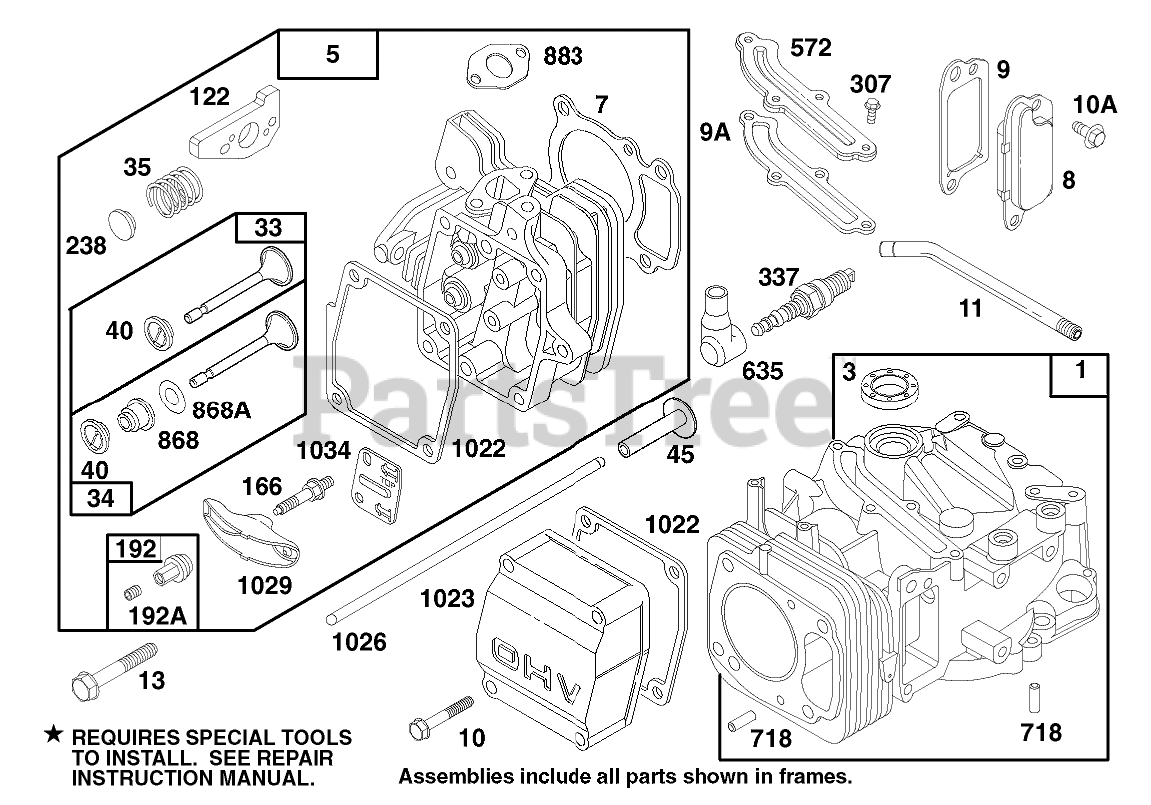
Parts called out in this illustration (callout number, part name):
1	CYLINDER ASSEMBLY
3	SEAL - OIL
5	CYLINDER HEAD
7	CYLINDER HEAD GASKET
8	BREATHER ASM
9	BREATHER GASKET
9A	GASKET-BREATHER
10	HEX HEAD SCREW
10A	HEX HEAD SCREW
11	TUBE - BREATHER
13	CYLINDER HEAD SCREW
33	EXHAUST VALVE
34	INTAKE VALVE
35	VALVE SPRING
40	SPRING RETAINER
45	VALVE TAPPET
122	ADAPTER ASSEMBLY
166	ROCKER ARM STUD
192	NUT - HEX SPECIAL
192A	Screw-Set
238	VALVE CAP
307	SCREW - SEM
337	PLUG-SPARK
572	BAFFLE - CYCLINDER
635	SPARK PLUG ELBOW
718	DOWEL - SLEEVE
868	SealAssy-Valve
868A	Seal-Valve
883	EXHAUST GASKET
1022	ROCKER COVER GASKET
1023	COVER - VALVE
1026	PUSH ROD
1029	ROCKER ARM
1034	PUSH ROD GUIDE
